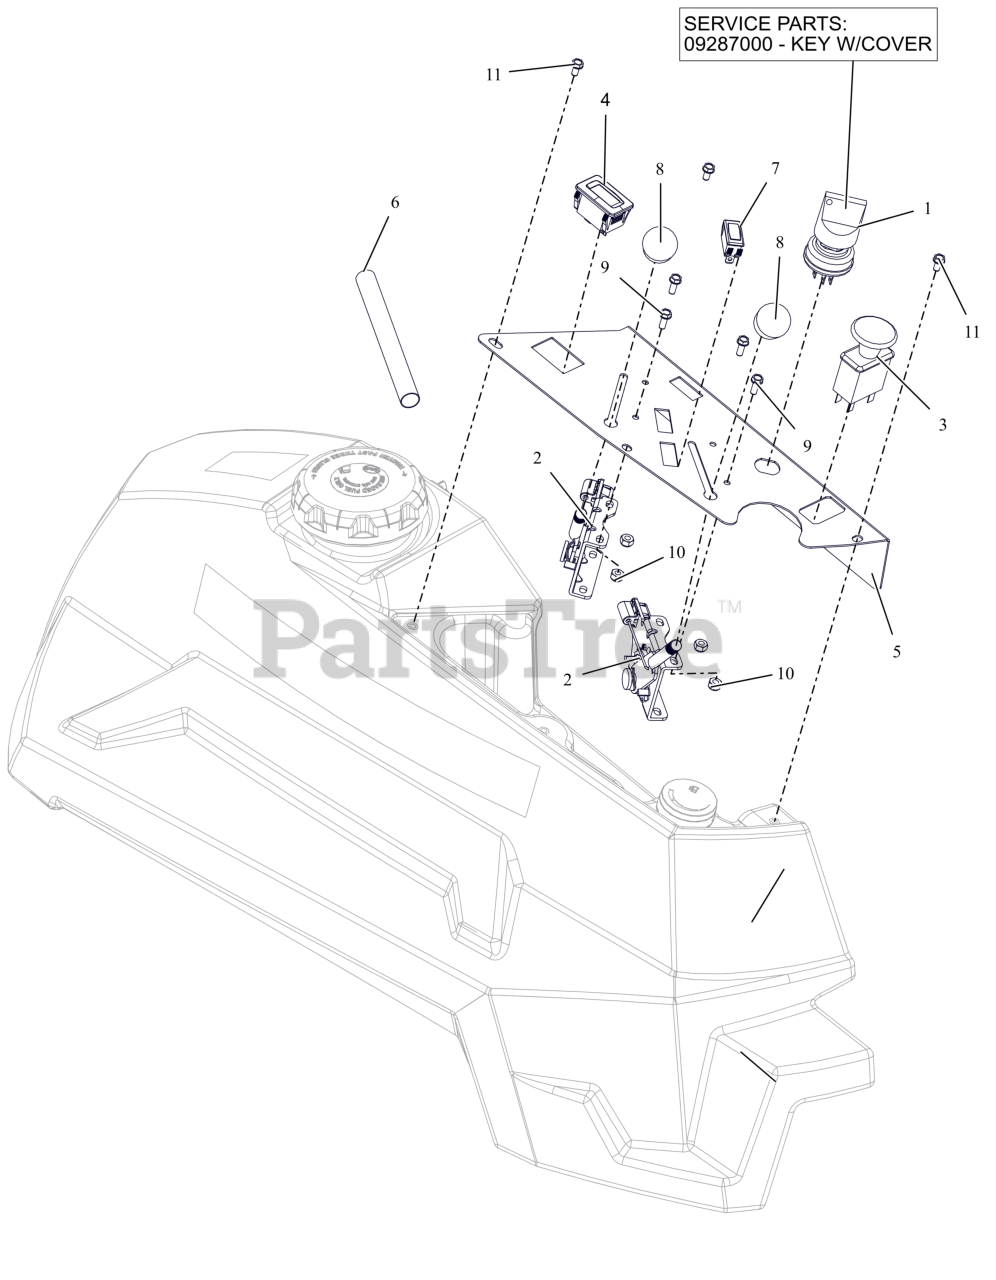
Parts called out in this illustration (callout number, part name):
1	SWITCH, IGNITION
1	KEY, W/ SHIELD
2	CABLE, PRO-CTRL 43.00"
3	SWITCH, CLUTCH
4	HOUR METER
5	PT400 CONTROL PANEL - RED
6	SLEEVE, THERMAL 6"
7	LIGHT, INDICATOR (RED)
8	KNOB-CONTROL-BLACK .38-16X.50
9	BLT, HWH #10-24X.50 ZCC
10	NUT-LK-NYL #10-24 G2 ZCC
11	SCR-MCH 10-24X.38 HWHSTAINLESS
